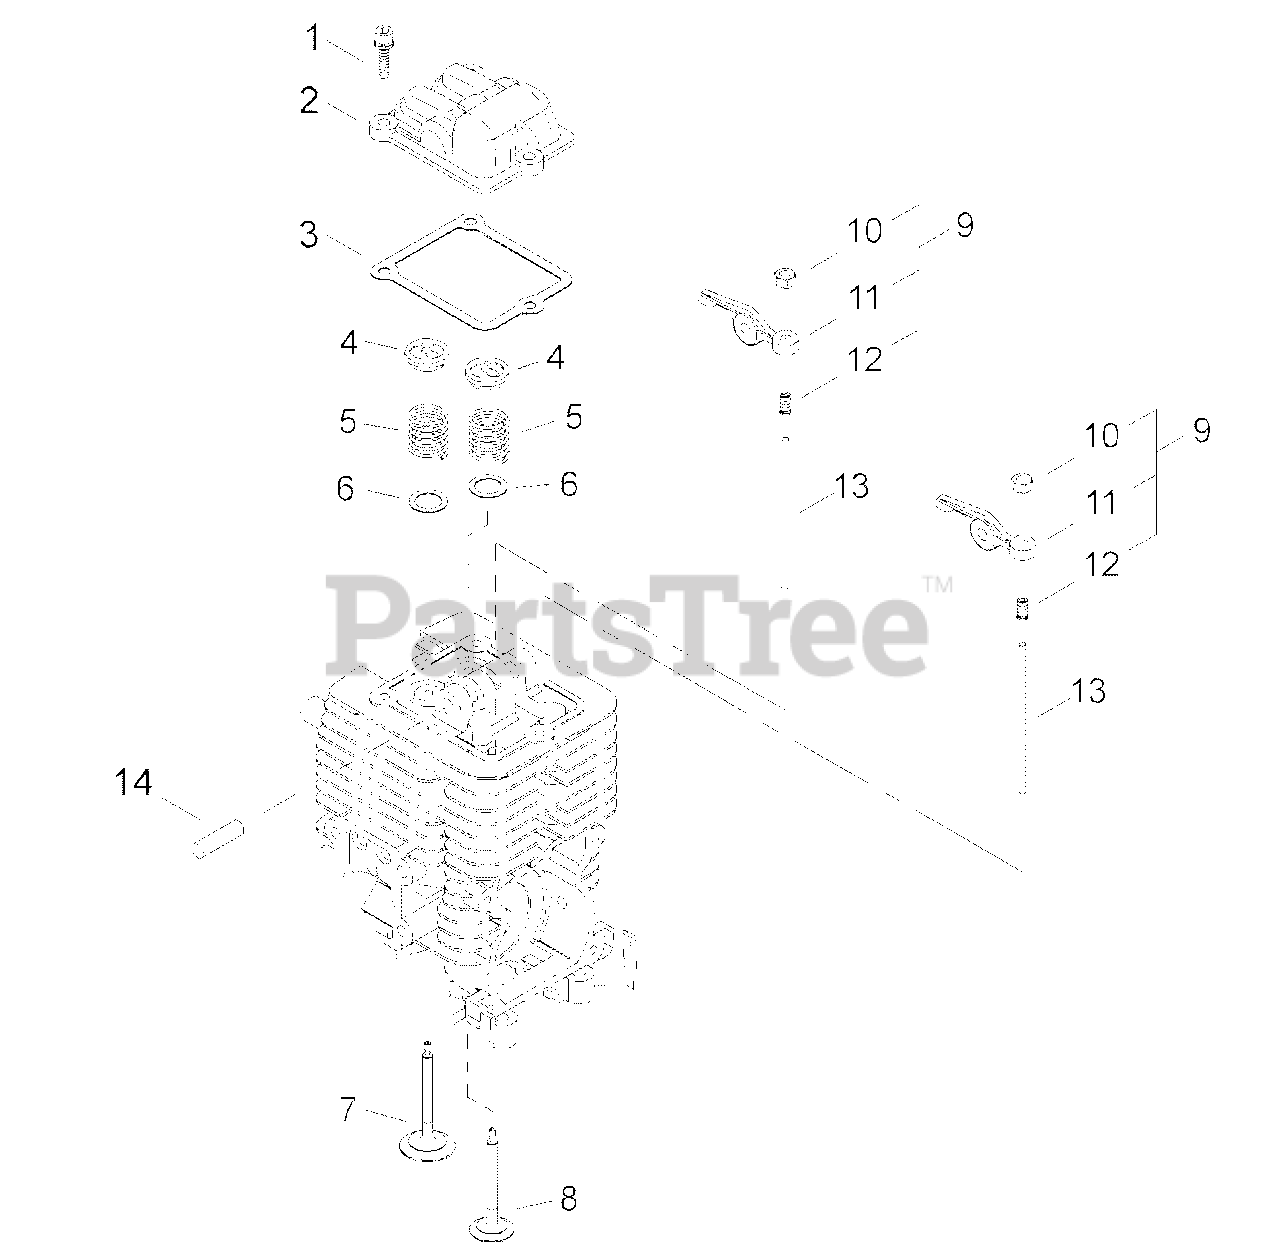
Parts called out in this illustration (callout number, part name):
1	SCREW - 4X14
2	COVER, ROCKER ARM
3	GASKET
4	RETAINER, VALVE
5	SPRING, VALVE
6	WASHER, VALVE - 9
7	VALVE, INTAKE
8	VALVE, EXHAUST
9	ROCKER ARM ASSY
10	LOCKNUT, ADJUSTER
11	ARM, ROCKER
12	SCREW, ADJUST
13	PUSHROD
14	SHAFT, ROCKER ARM - 5X37.8
